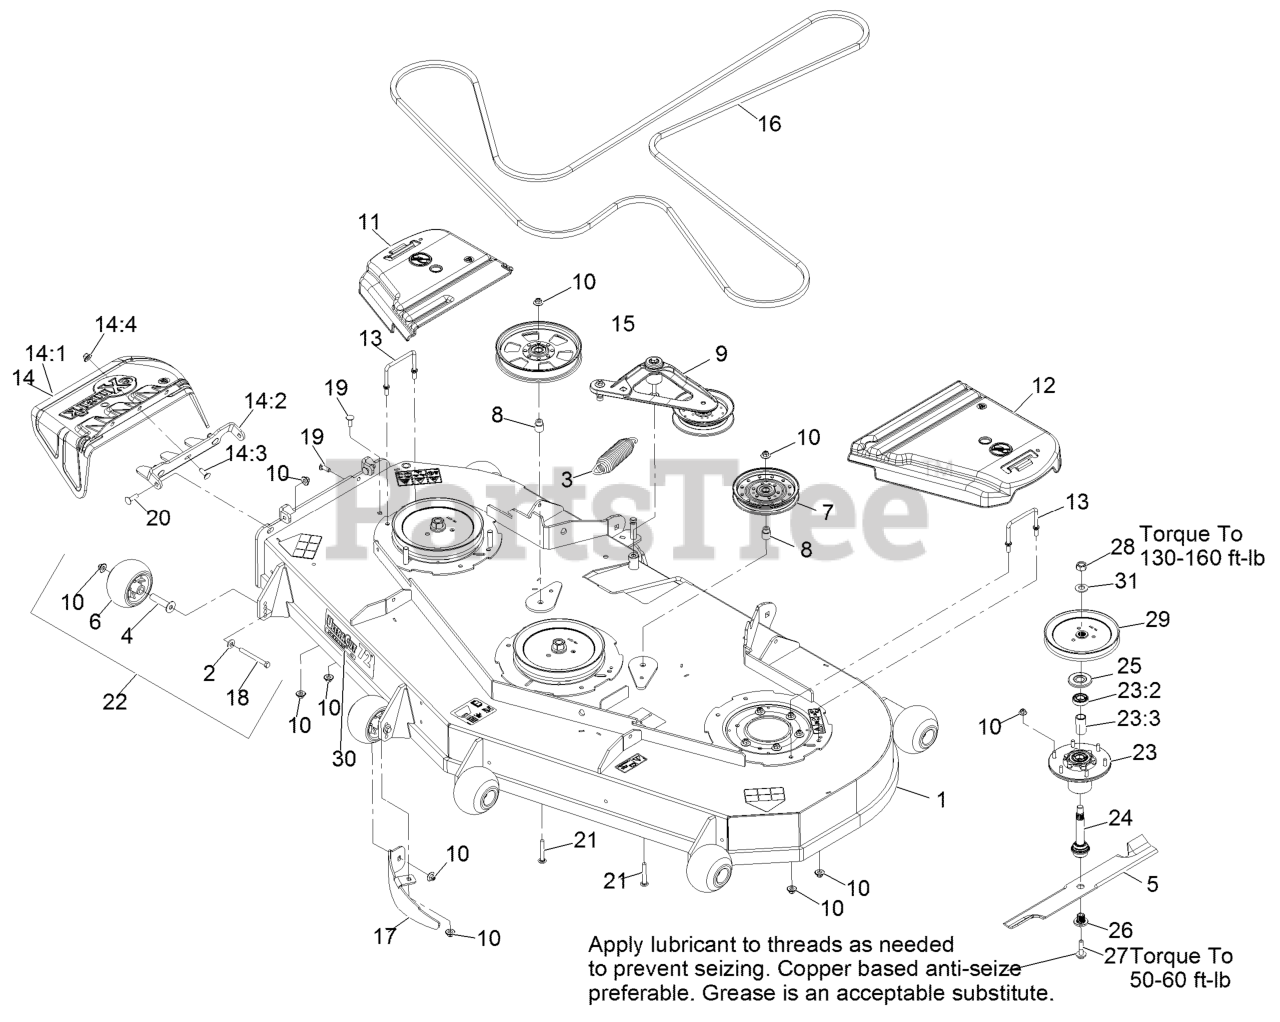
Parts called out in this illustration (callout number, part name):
1	ASM,DECK W/DECALS 724
2	WASHER-BELLEVILLE
3	SPRING-EXTENSION
4	AXLE, ROLLER
6	ROLLER-SCALP, ANTI
8	BUSHING-IDLER
9	DECK IDLER ASM
10	Nut-Nyloc 3/8-16 Flg
11	COVER-BELT, RH
12	COVER-BELT, LH
13	WIREFORM-COVER
14	ASM,DISCHARGE CHUTE
14:1	CHUTE,DISCHARGE
14:2	BRACKET,DISCHARGE CHUTE
14:3	SCREW-CARR
14:4	Nut-Nyloc 3/8-16 Flg
15	PULLEY-IDLER, FLAT
16	BELT-V
17	BAFFLE-DOGLEG, LZ72
18	SCREW-HH 3/8-16 X 3 3/4 GR 8
19	SCREW-CARR
20	Bolt-Carriage 3/8-16 X 1 1/4
21	SCREW-CARR
22	KIT, ANTI-SCALP ROLLER
23	ASM-CUTTER HSG WITH BEARINGS
23:2	BEARING-BALL
23:3	SPACER-BEARING
24	ASM-SPINDLE AND SEAL
25	GUARD,BEARING TOP .989
26	BUSHING,SPLINED
27	SCREW,SEMS 1/2-20 X 2.19
28	NUT-HEX
29	SHEAVE,BLADE DRIVE 8.74
30	DECAL,ULTRACUT 72 SERIES
